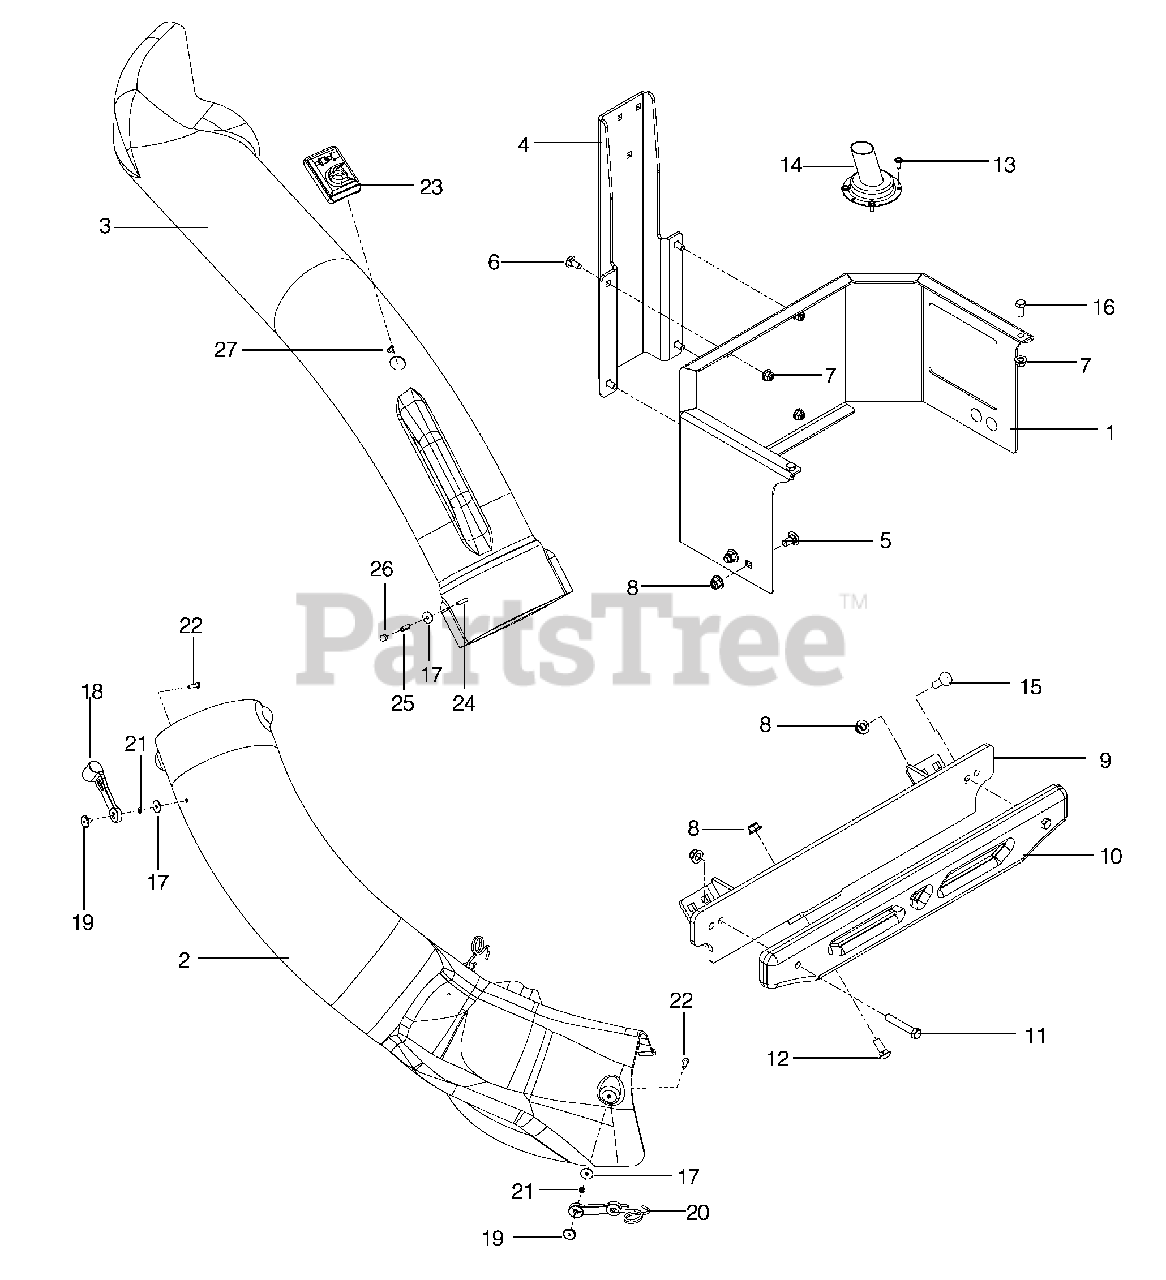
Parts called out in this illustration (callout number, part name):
1	GUARD, REAR
2	CHUTE, LOWER
3	CHUTE, UPPER
4	BRACKET, HANGER
5	RHSNB 3/8-16 x ¾
6	RHSNB 5/16-18 x ¾
7	NUT 5/16-18 HEX FLG NYLOC
8	NUT 3/8-16 HEX FLG
9	BRACKET, WEIGHT
10	CAST WEIGHT
11	HCS 3/8-16 x 2¼
12	RHSNB 3/8-16 x 1
13	SCREW, HEX WASHER HD
14	EXTENSION, MUFFLER
15	RHSNB 3/8-16 x 1¼
16	HCS 5/16-18 x ¾
17	WASHER 3/16 x ¾ x 16 GA
18	LATCH, HOOD
19	PLATED, WELD NUT
20	LATCH ASSY
21	WASHER 3/16 LOCK
22	SCREW #10-24 x .625
23	BAG INDICATOR
24	SCREW, #10- 24 x 11/8
25	SPACER, SPLIT
26	NUT, ACORN #10- 24
27	SCREW, SPECIAL #10-14 x ½
